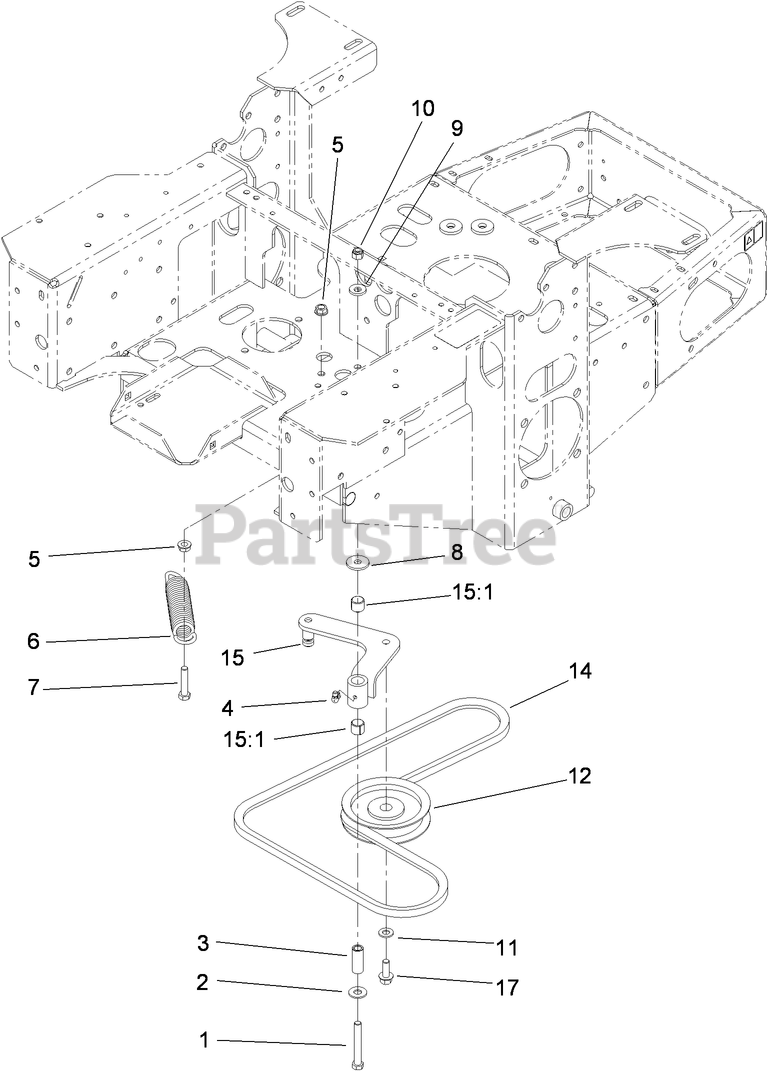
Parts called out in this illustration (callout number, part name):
1	SCREW-HH
2	WASHER-FLAT
3	BUSHING
4	FITTING-GREASE, 90 DEG
5	NUT-HHF, WHIZ
6	SPRING-EXTENSION
7	SCREW-HH
8	WASHER
9	WASHER-BELLEVILLE
10	NUT-LOCK, NI
11	WASHER-FLAT
12	PULLEY-IDLER
15	IDLER ARM ASM
15:1	SLEEVE-BEARING
17	SCREW-HHF
